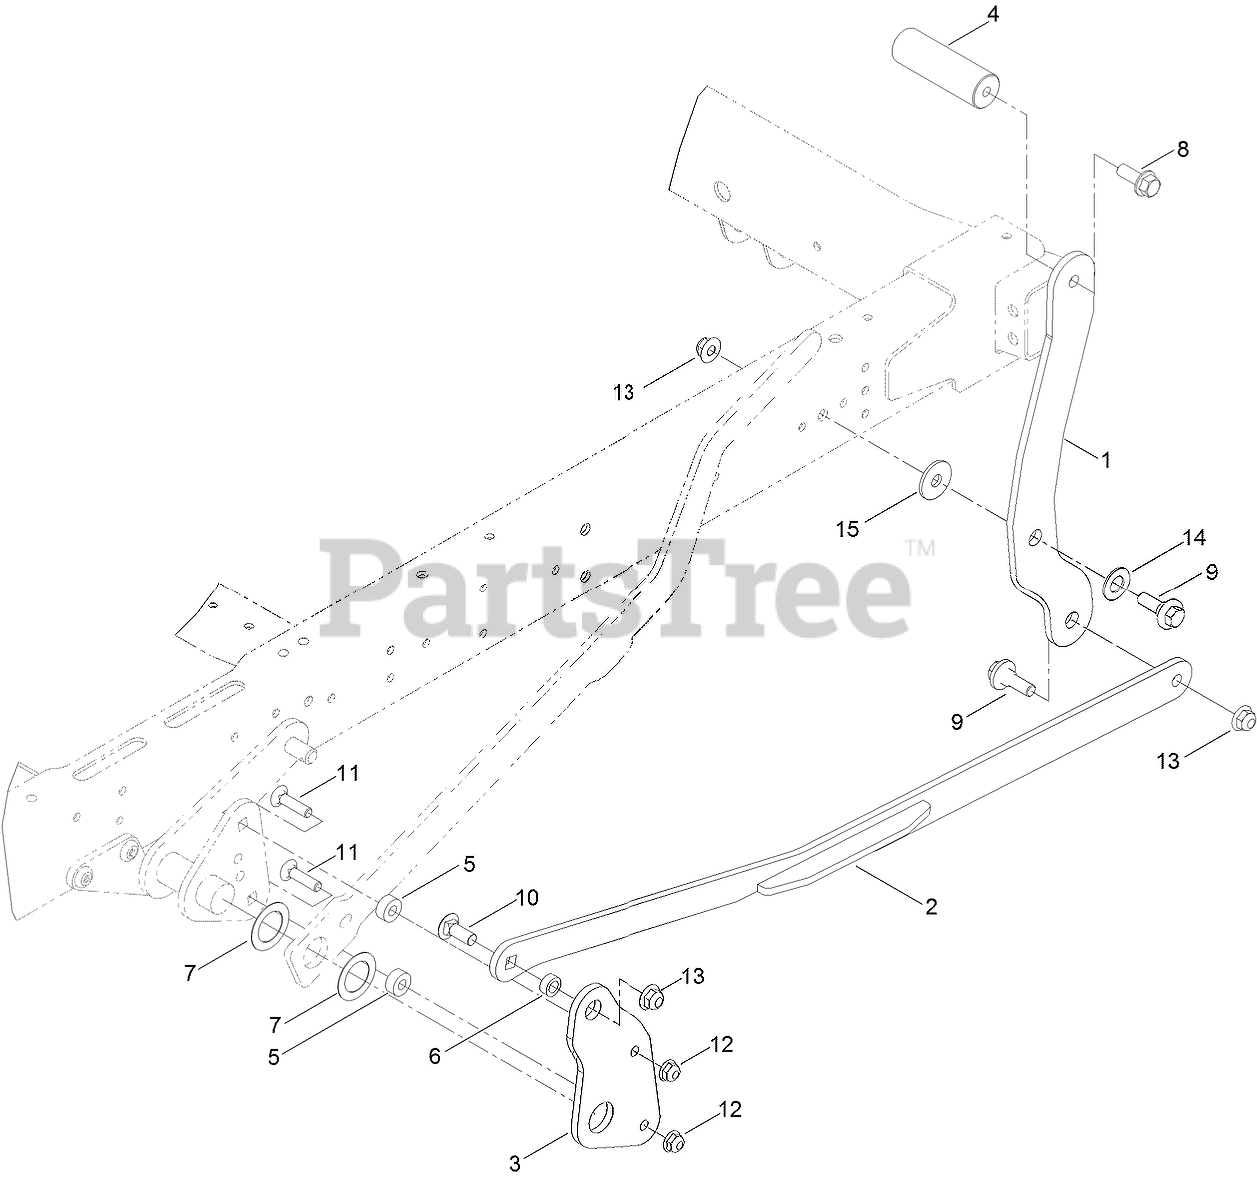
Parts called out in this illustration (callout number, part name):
1	PEDAL-LIFT
2	LINK ASM
3	PLATE-FOOTLIFT
4	PEDAL-FOOT LIFT
5	SPACER
6	SPACER
7	WASHER-THRUST
8	SCREW-HHF
9	SCREW-SHOULDER
11	BOLT-CARRIAGE
12	NUT-HF
13	NUT-HF, NI
14	WASHER-NYLON
15	WASHER-HARDENED, CZ
